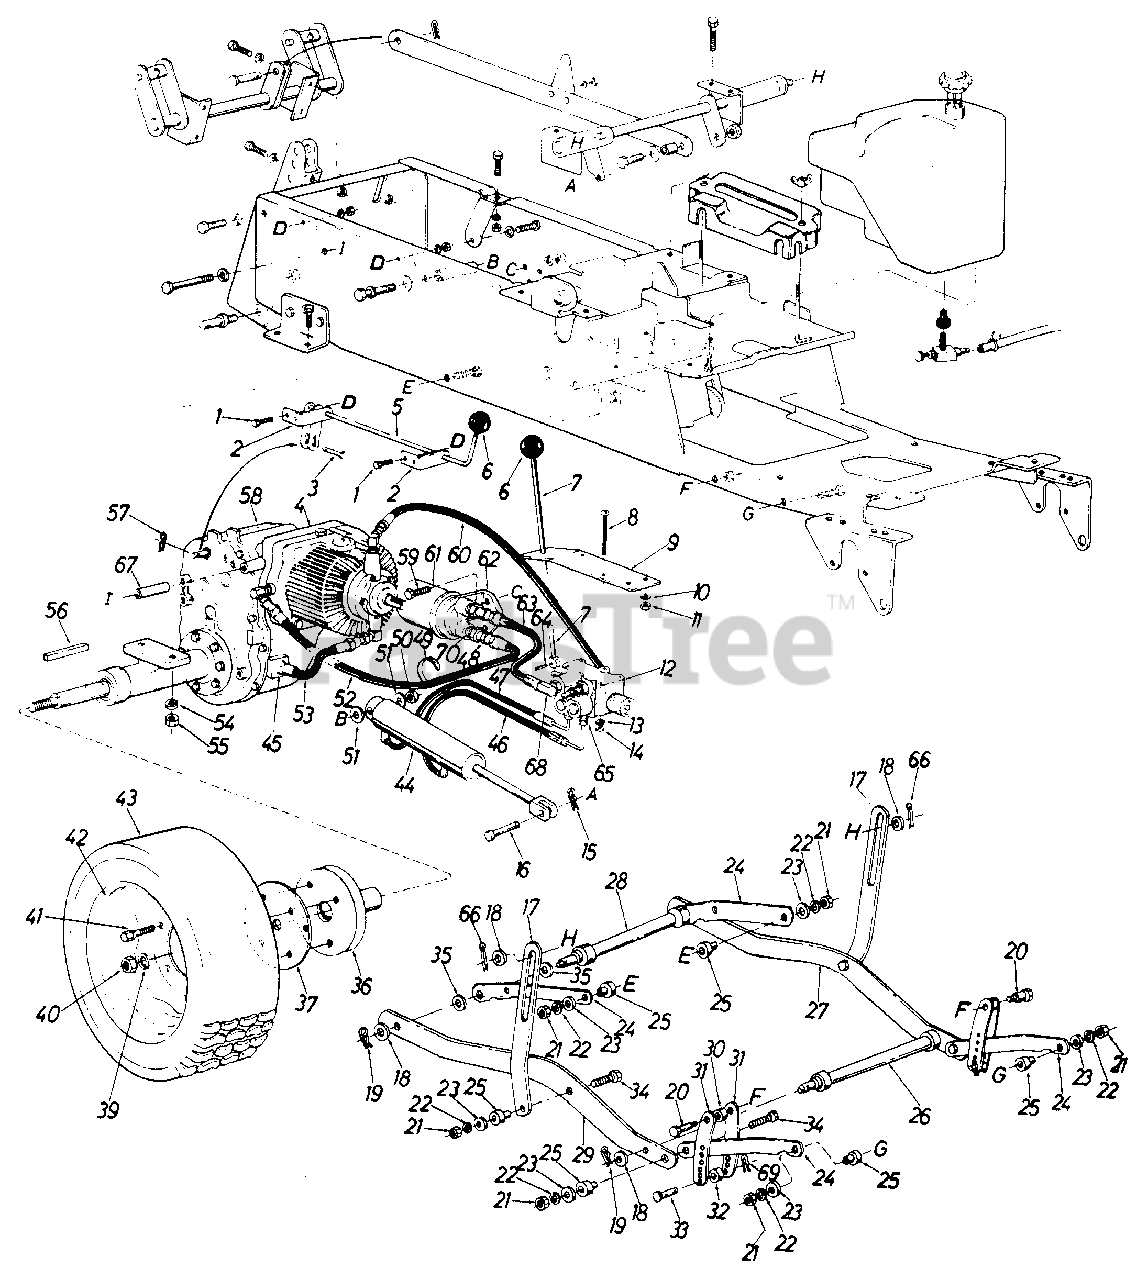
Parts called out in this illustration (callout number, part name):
1	Hex Scr. 1/4-20 x .75" Lg.
4	Hydrostatic Pump Comp.
5	Hi-Lo Control Handle Ass'y.
6	Ball Knob
7	Cylinder Control Handle Ass'y.
8	Truss Mach. Scr. 1/4-20 x 3.00" Lg.*
11	Hex Nut 5/16-18 Thd.*
12	Valve Ass'y. Comp.
13	L-Wash. 1/4" Scr.*
14	Hex Nut 1/4-20 Thd.*
15	Hairpin Cotter 1/2" Dia.
16	Clevis Pin 1/2" Dia.
19	Hairpin Cotter
20	Shld. Scr. .498 Dia. x .66
21	Hex Nut 3/8-24 Thd.*
22	L-Wash. 3/8" Scr. H.D.
23	Fl-Wash. .38 I.D. x 1.00" O.D.
26	Cross Shaft Ass'y. Front
33	Clevis Pin 3/8" Dia.
34	Hex Scr. 3/8-24 x 1.50" Lg. Grade 5
35	Fl-Wash. .62" I.D. x 1.25" O.D. x .020
39	L-Wash. 3/4" Scr.*
40	Hex Ins. L-Nut 3/4-16 Thd.
41	Wheel Lug Bolt 1/2-20 x 1.50 " Lg.
44	Hydraulic Cylinder
45	7/8-14 UNF-2A Thd. 5/8 Tube Fitti ng
46	Valve to Cylinder Hose 20" Lg.
47	Valve to Cylinder Hose 20" Lg.
48	Bushing Reducer 1/2-14 NPTF to 3/8-18 NPTF
49	Cable Tie
50	Hex Jam Nut 1/2-20 Thd.
51	Fl-Wash. .50" I.D. x 1.25 O.D.
52	Filter Return Hose 24" Lg.
53	Pump Tube Ass'y.
54	L-Wash. 3/8" Scr.
55	Hex Nut 3/8-16 Thd.
56	Sq. Key 1/4" x 1/4" X 2.00" Lg.
57	Hairpin Cotter 1/4" Dia.
58	Peerless Transaxle
59	Hex Scr. 5/16-18 x 1.25" Lg .
60	Pump to Valve Hose
61	Fram Filter Ass'y. PH-16
63	Valve to Filter Hose 8.38" Lg.
64	Spring Pin Spiral 1/8" Dia. x .81 " Lg.
65	Flare Adapter
66	Cotter Pin 118" Dia. x 1.00" Lg .
68	Adapter 9/16-18 to 9/16-18
69	Hairpin Cotter
70	Reducer 1/2-3/8 NPT
